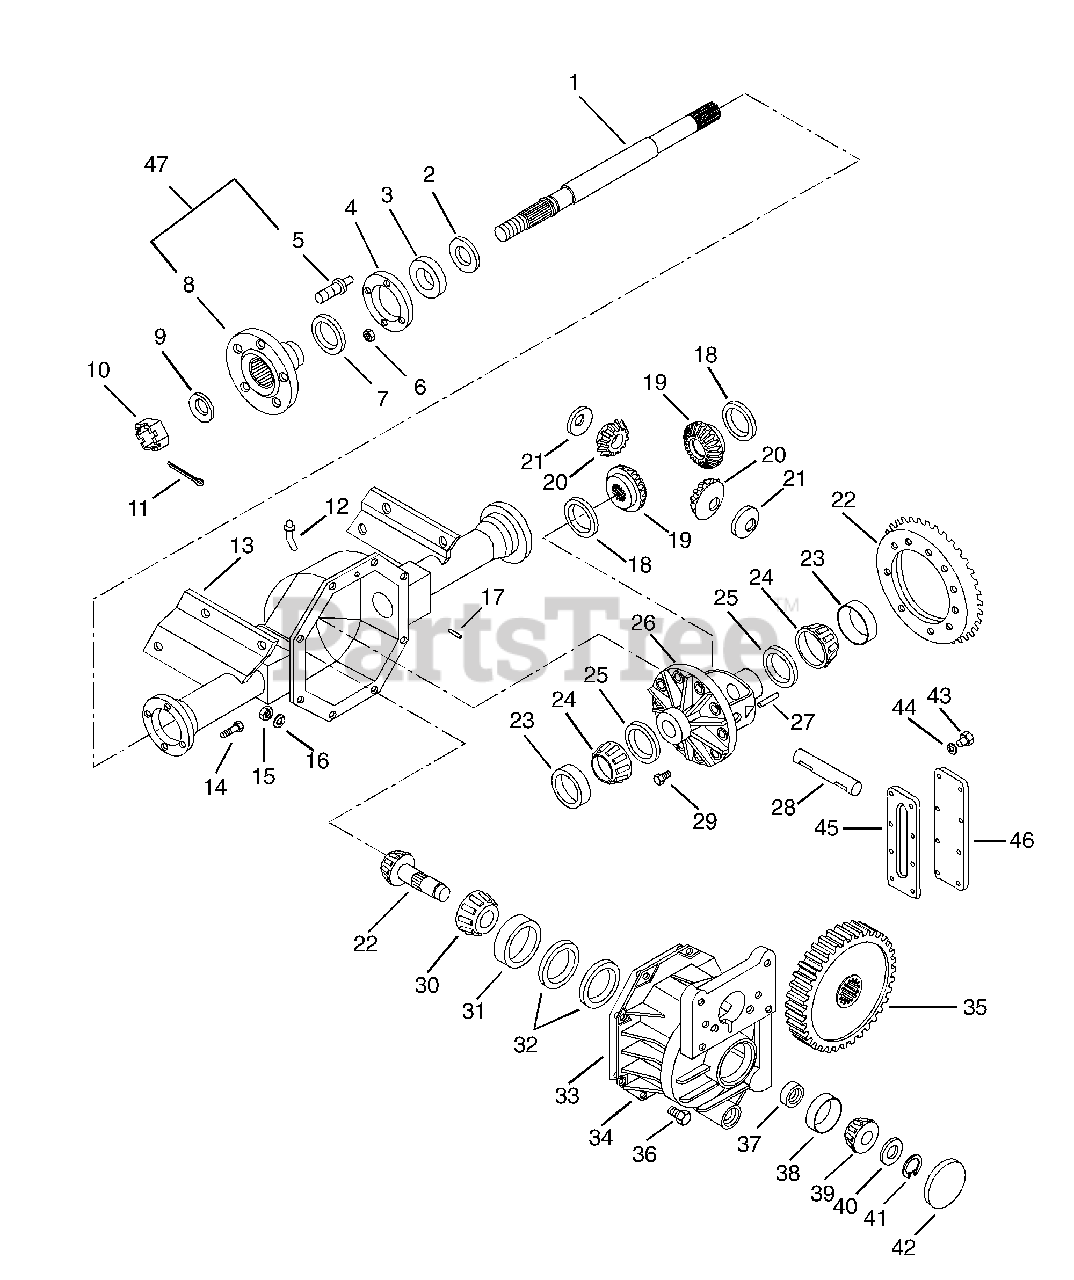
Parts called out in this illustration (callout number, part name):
1	AXLE SHAFT LH
1	AXLE SHAFT RH
2	SEAL 1.183X1.183X.265
3	BRG-CONE 46MMX17MM
4	GASKET-SEE LETTER L-307
5	CARRIER LUG BOLT
6	NUT-LK-FLG .312-24 GR C
7	FELT SEAL
8	AXLE FLANGE
9	WSHR-FL-STL .890X1.500X.1196YZ
10	NUT-SL .875-14 YWZC
11	@PIN-CTR .15X1.50 YWZC
13	LOWER HOUSING
14	BLT-HEX .31-24X1.25 GR8
15	NUT-HEX .312-18
16	WSHR-LK-INT .313X.030 PL
17	DOWEL PIN
18	WSHR-FL-STL 1.578X2.375X.031
19	SIDE GEAR
20	BEVEL GEAR
21	WSHR-BLVL .703X1.593X.031
22	PINION & GEAR
23	BRG-CUP 2.892X.580
24	BRG-CONE 1.63X.78
26	DIFFERENTIAL CASE
27	LOCK PIN
28	PINION SHAFT
29	BLT .38-24X.812 DANA
30	BRG-CONE 1.188X.84
31	BRG-CUP 2.532X.656
34	FRONT HOUSING W/BEARING CAP &
35	SPUR GEAR
36	BLT-HEX .31-18X1.00 PL GR5
37	FRONT PINION BEARING SPACER
38	BRG-CUP 1.968X.550
39	BRG-CONE .844X.72
40	SHIM ASSEMBLY
41	RG-RTNG-EXT .813X.042
42	CUP PLUG
43	TAPTITE M5-0.8X16MM H-FL-PL
44	WSHR-LK-EXT 12X.025 PL
46	SIDE COVER
47	AXLE FLANGE ASSEMBLY
